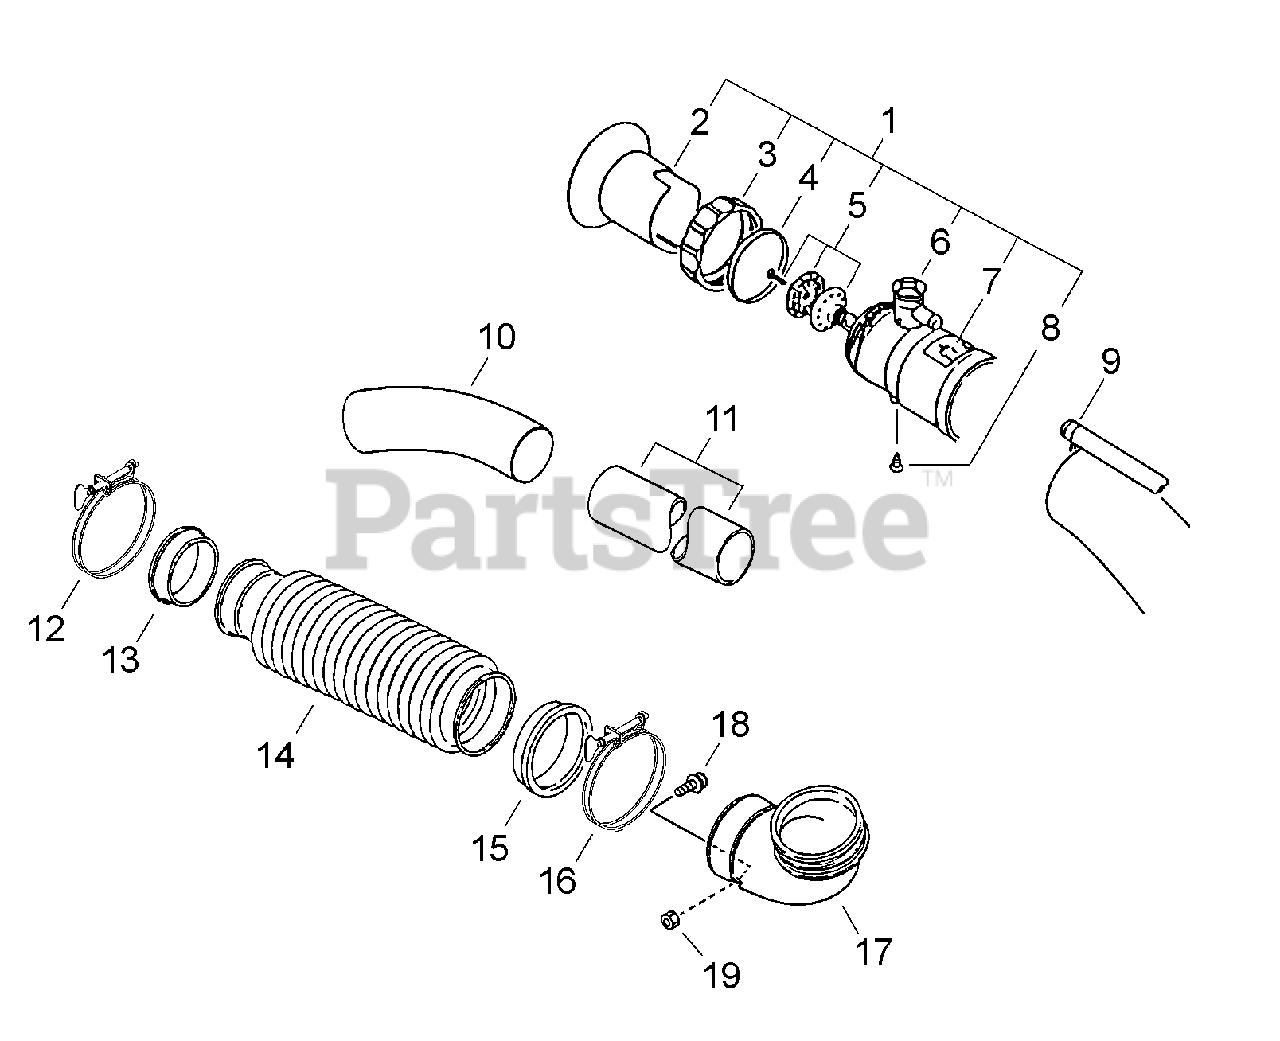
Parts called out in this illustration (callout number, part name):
1	MISTING NOZZLE ASSY
5	NOZZLE ASSY
6	CONTROL, VOLUME
7	LABEL - MIST
8	SCREW - 5X12
10	TUBE, BLOWER - CURVED
11	TUBE, BLOWER - STRAIGHT
12	CLAMP
14	TUBE, BLOWER - FLEXIBLE
16	CLAMP
17	TUBE, BLOWER - ELBOW
18	SCREW - 5X14
